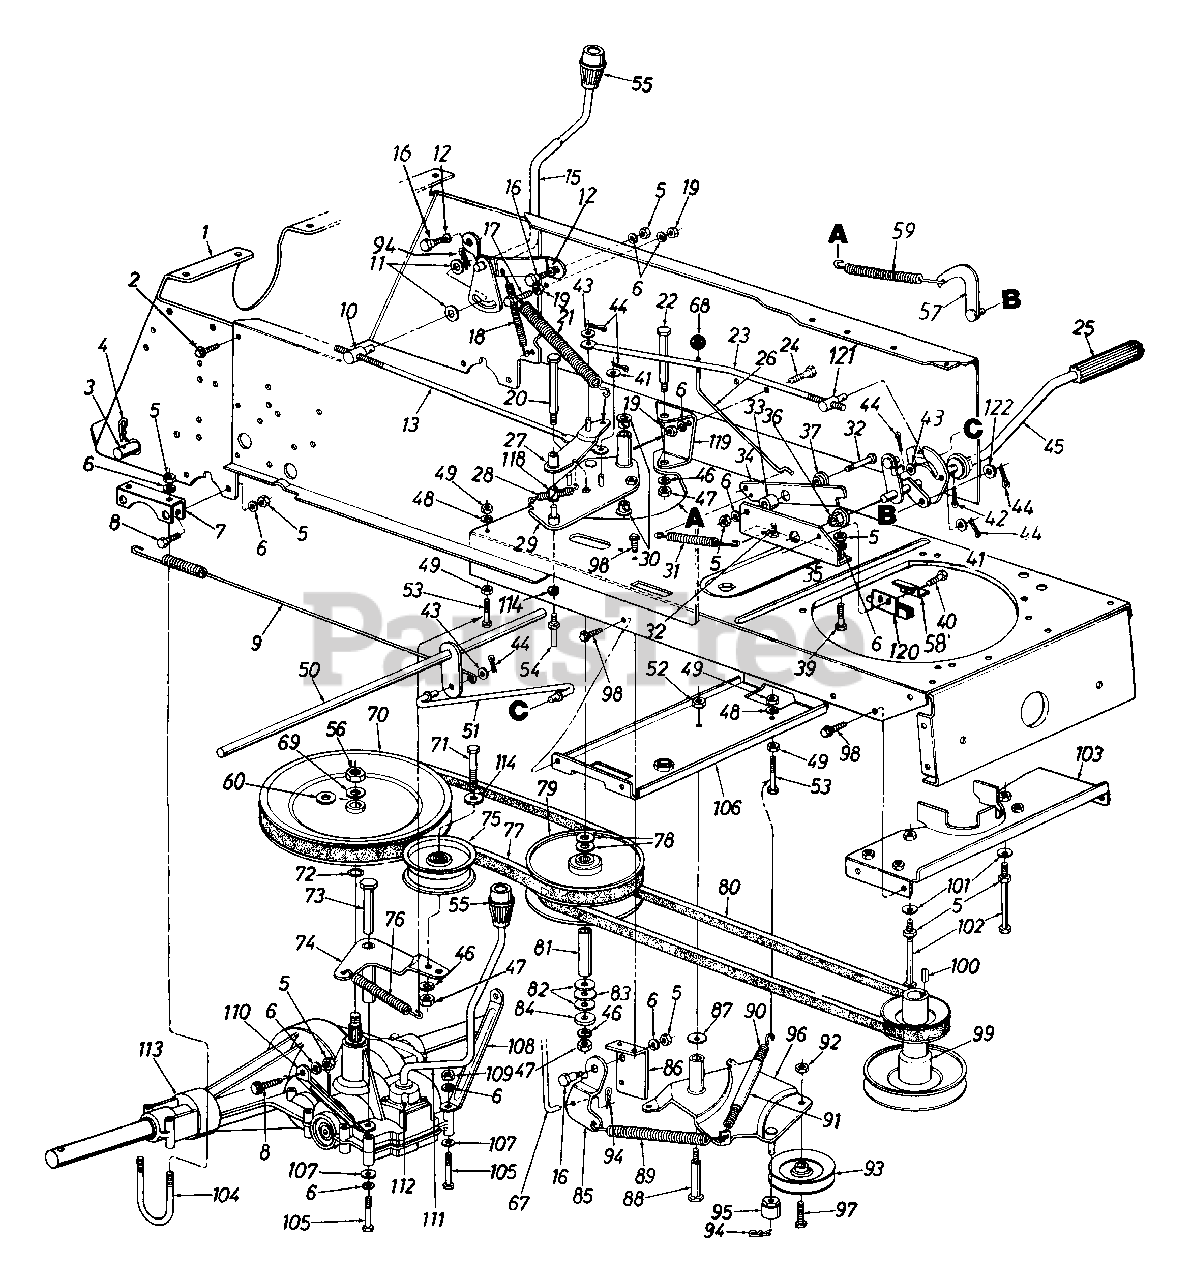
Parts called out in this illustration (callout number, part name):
3	Hitch Rod
4	Hitch Pin Clip
5	Hex Nut 5/16-18 Thd.
6	L-Wash. 5/16" I.D.
7	Transaxle Bracket
8	Hex Bolt 5/16-18 x .75" Lg. (Gr. 5)
9	Brake Extension Spring
10	Adjustment Ferrule 3/8-24 Thd.
11	Fl-Wash. .385" I.D. x .87"
12	Spr. Wash. .445" I.D. x .75" O.D.
13	Speed Control Link (Rear)
15	Speed Selector Lever Ass'y.
16	Shld. Bolt .437" Dia. x .162"
17	Hex Bolt 5/16-24 x 1.25" Lg.
18	Extension Spring 3.9" Lg.
19	Hex Nut 5/16-24 Thd. (Gr. 5)
20	Hex Bolt 3/8-24 x 4.5" Lg.
21	Extension Spring 11" Lg.
22	Shld. Bolt .625" Dia. x 3.5" Lg.
23	Speed Control Link (Front)
24	Hex Bolt 5/16-24 x .75" Lg.
25	Foot Pad
26	Parking Brake Link
29	Pulley Plate Ass'y.
30	Flanged Brg. .630" I.D.
31	Extension Spring 2.51" Lg.
32	Hex Bolt 5/16-18 x 1.25" Lg.
33	Spacer .34" I.D. x .88"
36	Hex Flange Brg. .634" I.D.
37	Shld. Spacer .5" Dia.
39	Hex Bolt 5/16-18 x .75" Lg.
40	Hex B-Tap Scr. #10 x 5/8 Lg.
41	Fl-Wash. .406" I.D. x .75" O.D.
42	Cotter Pin 1/8" Dia.
43	Fl-Wash. .34" I.D. x .68" O.D.
44	Cotter Pin 3/32" Dia.
47	Hex Nut 3/8-24 Thd.
48	L-Wash. 1/4" I.D.
49	Hex Nut 1/4-20 Thd.
50	Brake Link Bracket
51	Front Brake Rod Link
52	Hex Cent. L-Nut 3/8-16 Thd.
53	Hex Bolt 1/4-20 x 2.0" Lg.
54	Belt Guard Pin
55	Shift Knob
56	Hex Jam Nut 9/16-18 Thd.
57	Foot Pedal Brkt. Ass'y.
58	Switch Plate
59	Ext. Spring 5.2" Lg.
60	Fl-Wash. .635" I.D. x 1.12" O.D.
67	Deck Control Rod
68	Ball Knob Brake
69	Bell-Wash. 9/16" I.D. x 1.25"
70	V-Pulley 9 1/4" O.D.
71	Hex Bolt 3/8-24 x 1.75" Lg.
72	Wire Ring
73	Shld. Bolt 5/16-24 Thd.
74	Idler Brkt. Ass'y.
75	Flat Idler 3.5" O.D.
76	Extension Spring 6.12" Lg.
77	V-Belt
78	Teflon Washer 1.20" O.D.
79	Variable Speed Pulley 6" Dia.
80	V-Belt
81	Pivot Bushing
82	Fl-Wash. .56" I.D. x 1.0" O.D.
83	Thrust Brg. .56" I.D. x 1.25"
84	Retainer Cup
85	Deck Control Pivot Brkt.
86	Parking Brake Mtg. Brkt.
87	Bell-Wash. .38" I.D. x .88" O.D.
88	Shld. Bolt .498" Dia. x 2.05"
89	Extension Spring 6.12" Lg.
90	Extension Spring 6.37" Lg.
91	Convoluted Conduit 4" Lg.
92	Hex Cent. L-Nut 3/8-24 Thd.
93	V-Belt Idler
94	Internal Cotter Pin
95	Spacer
96	ldler Brkt. Deck Ass'y.
97	Hex Bolt 3/8-24 x 1.5" Lg.
98	Hex TT-Tap Scr. 1/4-20 x .5"
99	Engine Pulley
100	Sq. Key 1/4 x 1.5" Lg.
101	Bell-Wash. .345" I.D. x .88"
102	Hex Bolt 5/16-18 x 5.25" Lg.
105	Hex Bolt 5/16-24 x 2.25" Lg.
106	Deck Idler Support Brkt.
107	Fl-Wash. .344" I.D. x .62" O.D.
108	Front Trans. Support Brkt.- L.H.
109	Hex Nut 5/16-24 Thd.
110	Front Trans. Support Brkt.- R.H.
111	Shift Lever Ass'y. Complete
112	Socket Hd. Cap Scr. #10 x 24
113	2-Speed Transmission Comp.
114	Fl-Wash. 3/8" I.D. x 1.0" O.D.
118	Nyliner Flanged Brg.
119	Variable Speed Support Brkt,
120	Safety Switch (Clutch)
121	Adjustment Ferrule 3/8-24 Thd.
122	Fl-Wash. .344" I.D. x .62" O.D.
